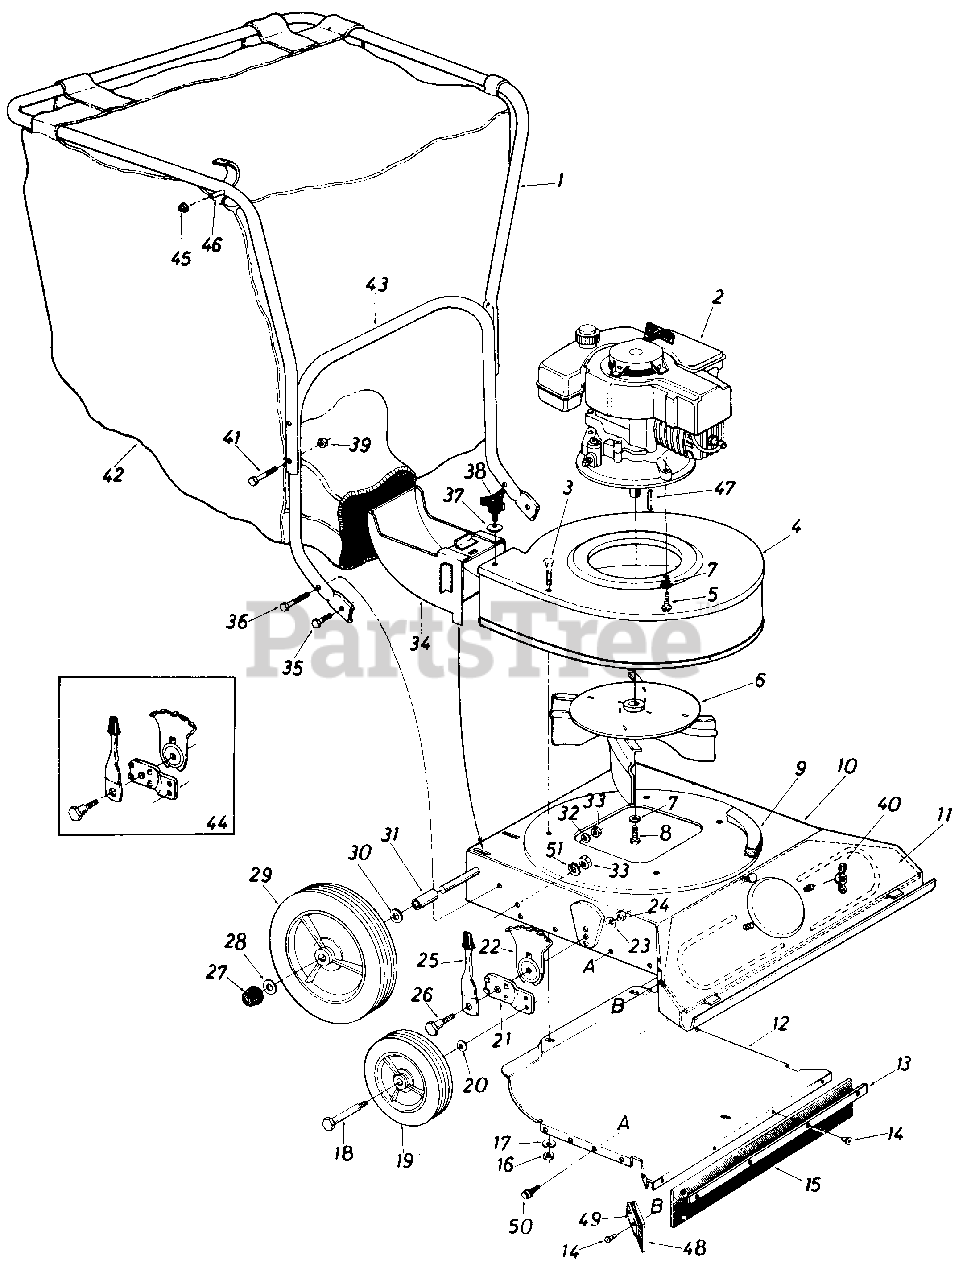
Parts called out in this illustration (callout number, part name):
1	Upper Handle (Painted)
2	Engine
3	Carriage Bolt 5/16-18 x .62" Lg.
4	Blower Housing Ass'y.
5	Hex Tap Scr. 3/8-16 x 1.00" Lg.
6	Impeller Ass'y.
7	L.-Wash. 3/8" I.D.
8	Hex Bolt 3/8-24 x 1.0" Lg. w/Patch
9	P.V.C. Foam Strip (4-Pcs. 12" Lg. )
10	Vacuum Deck Ass'y.
11	Front Baffle Ass'y.
12	Lower Baffle Ass'y.
13	Wiper Retaining Strip
14	Pop Rivet.188" Dia.
15	Nozzle Wiper Rear
16	Hex Nut 5/16-18 Thd.
17	Bell.-Wash..34" I.D. x.87" O.D.
18	Shld. Bolt 1/2" Dia. x 1.45" Lg. (3/8-16)
19	Wheel Ass'y. Comp. 8 x 1.75"-Front
20	Bell.-Wash. .39" I.D. x 1.12" 0. D.
21	Wheel Pivot Bar
22	Index Plate
23	Bell.-Wash. .39" I.D. x 1.12" 0. D.
24	Hex Nut 3/8-16 Thd.
25	Spring Lever Ass'y. w/Knob
26	Shoulder Bolt .500" x 7/16" Lg. (3/8-16)
27	Push Cap .50" Rod (Black)
28	Fl.-Wash. 1/2" I.D. x 1.0" O.D. x .06
29	Wheel Ass'y. Comp. 10 x 1.75"-Rear
30	Fl.-Wash. 1/2" I.D. x 1.0" O.D. x .06
31	Wheel Spacer 1/2" I.D. x 15/16" Lg.
32	Bell.-Wash. .39" I.D. x 1.12" 0. D.
33	Hex Nut 3/8-16 Thd.
34	Air DuctAss y.
35	Hex Bolt 3/8-16 x .75" Lg.
36	Hex Bolt 3/8-16 x 1.50" Lg.
37	Bell.-Wash. .34" I.D. x .87" O.D.
38	Thumb Scr. 5/16-18 x .75" Lg.
39	Hex Cent. L.-Nut 1/4-20Thd.
40	Wing Nut 1/4-20 (Plastic)
41	Hex Bolt 1/4-20 x 1.75" Lg.
42	Vacuum Bag (6.6 Bushel)
43	Lower Handle (Painted)
44	Height Adjuster Ass'y. Comp.-R.H.
45	Push Speed Nut .25" Dia.
46	Stud Pin .250" Dia. x 1.75" Lg.
47	Sq. Key 3/16 x 3/16 x l.OO"Lg.
48	Nozzle Wiper Side
49	Wiper Retaining Strip
50	Hex Wash. Hd. "F" Tap Scr. #10
51	L-Wash. 3/8" I.D.
